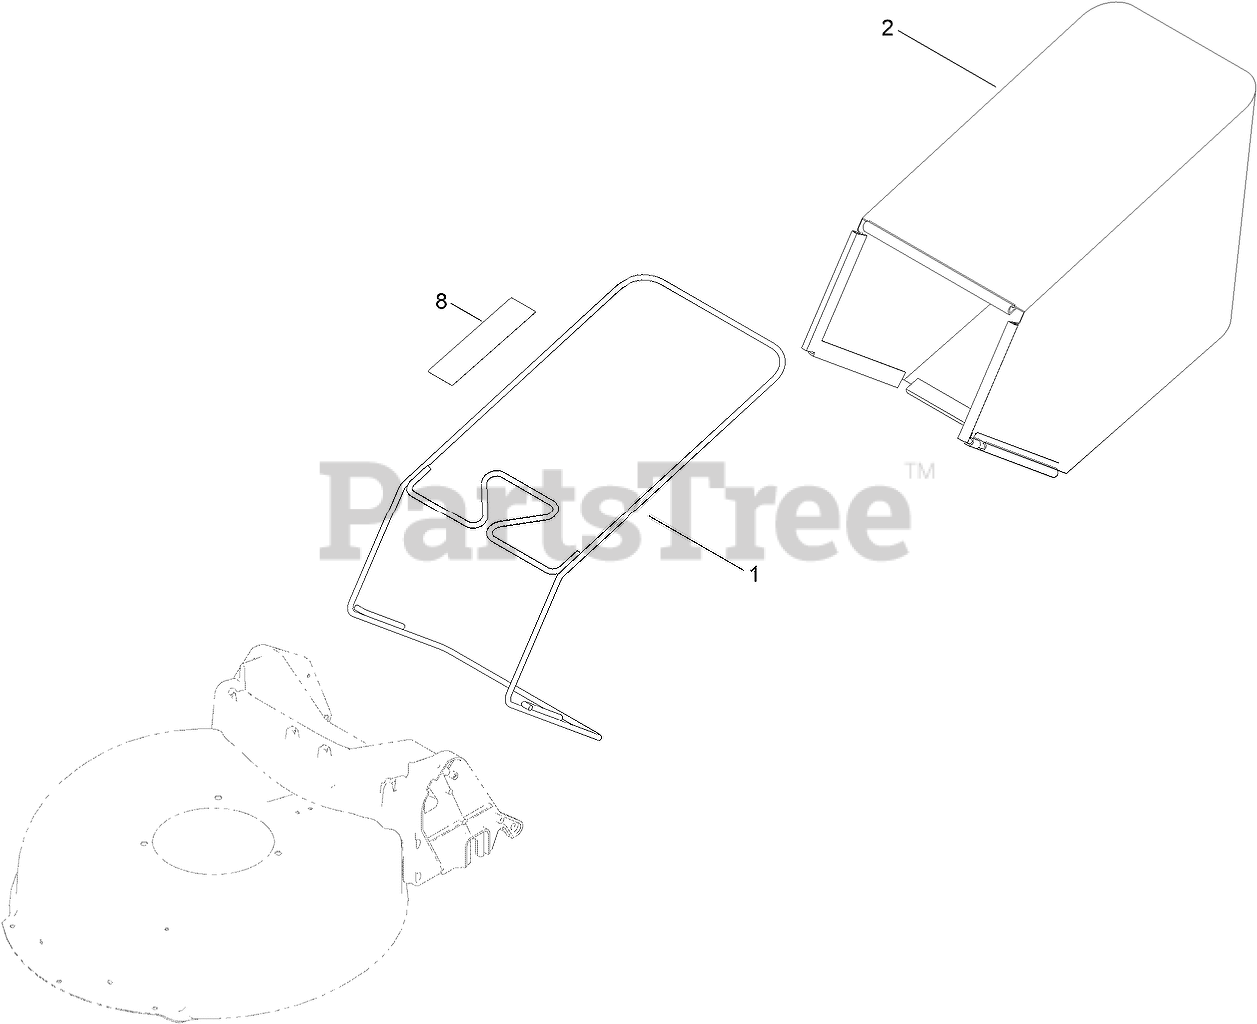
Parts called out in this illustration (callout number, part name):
1	FRAME-BAG
2	GRASS BAG ASM
8	Decal-Warning
